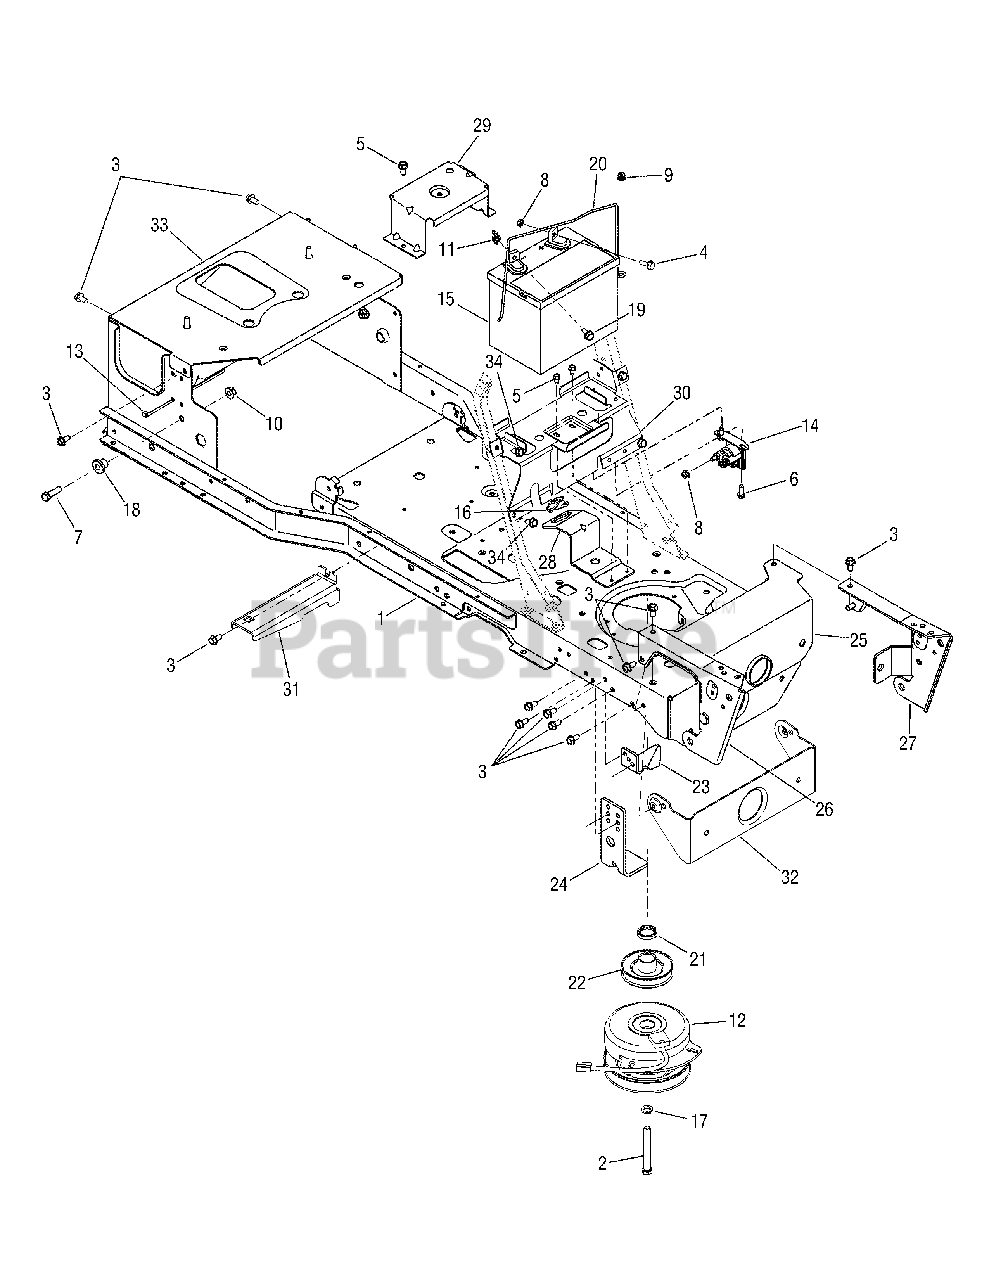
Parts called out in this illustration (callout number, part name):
3	Screw, Hex Wash. Hd. Tapp, 5/16-18 x .75
4	Screw, Hex Flange Hd. , 1/4-20 x .75 Gr5
5	Screw, Hex Wash. Hd. Tapp, 1/4-20 x .5
6	Screw, Hex Wash. Hd. Tapp, 1/4-20 x .75
7	Screw, Hex Cap, 3/8-16 x 1.25 Gr5
8	Nut, Hex Sems, 1/4-20
9	Nut, Hex Flange Insert Lock, 1/4-20 GrF
10	Nut, Hex Flange Insert Lock, 3/8-16 GrF
11	Nut, Wing, 1/4-20
12	Clutch, Electric PTO
13	Cable Tie
14	Solenoid, Start
15	Battery - Dry
16	Bushing, Steering Shaft
17	Washer, Lock, 7/16
18	Screw, Shoulder, .38 x 1.0 x .7
19	Screw, Shoulder, .25 x .15:1/4-20
21	Spacer, 1.37 x 1.00 x .25
22	Pulley, Engine
